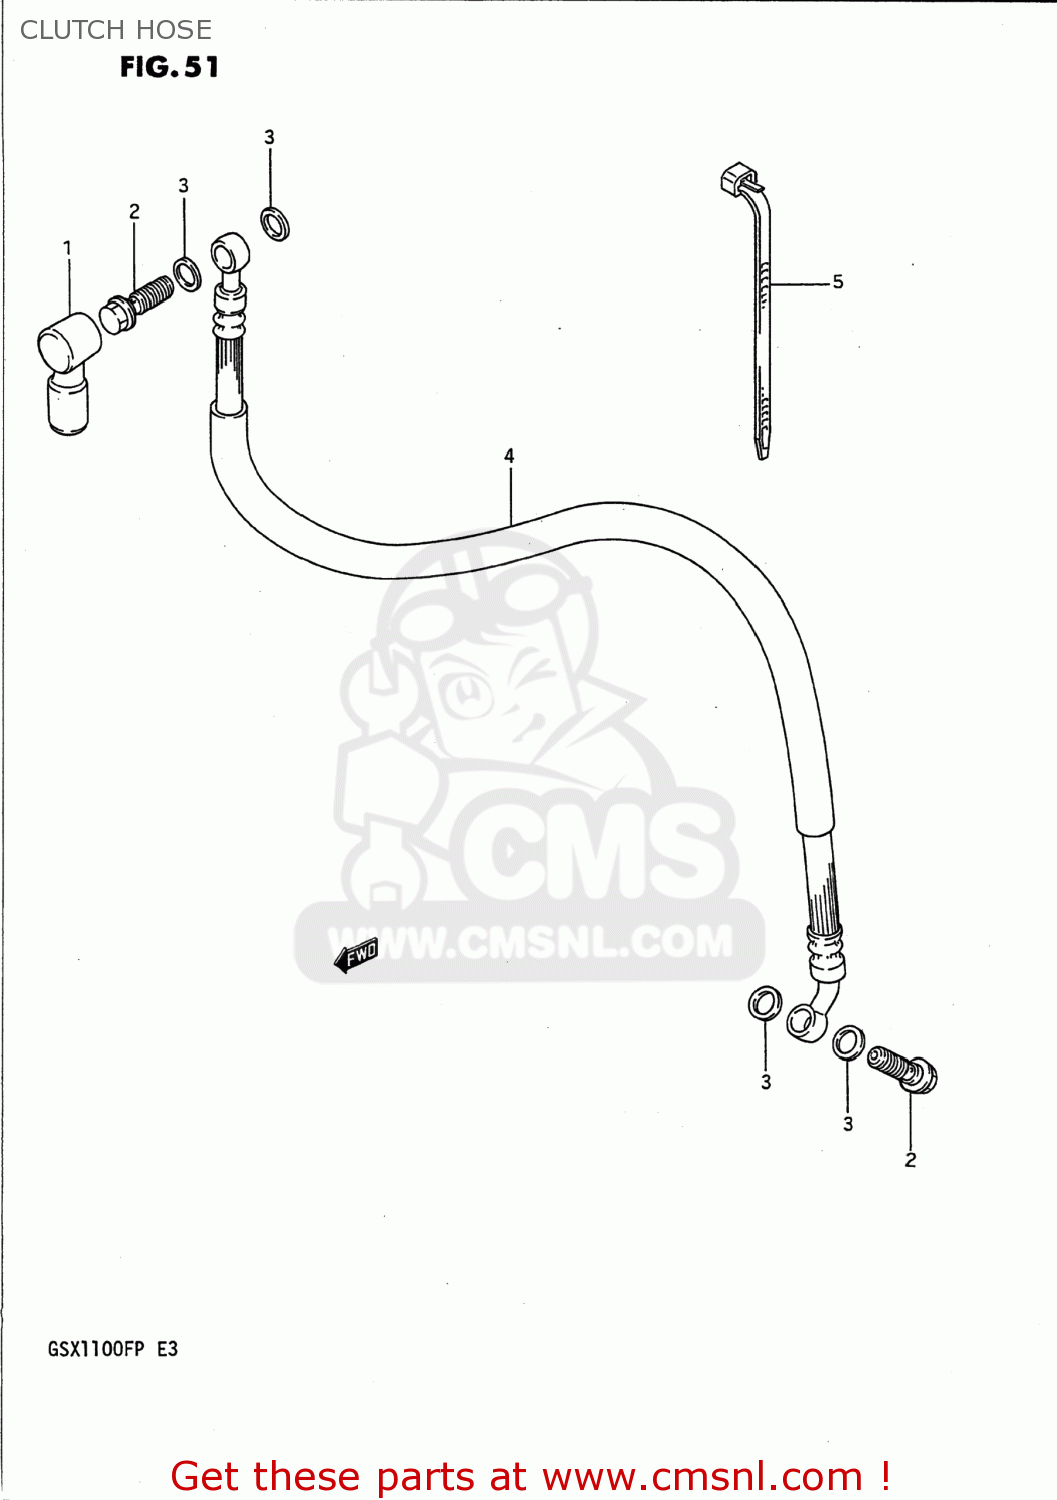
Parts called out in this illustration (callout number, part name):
1	BOOT,MASTER CYLINDER
2	BOLT UNION
3	WASHER(10X15X1.5)
4	HOSE,CLUTCH
5	CLAMP(L:165)
